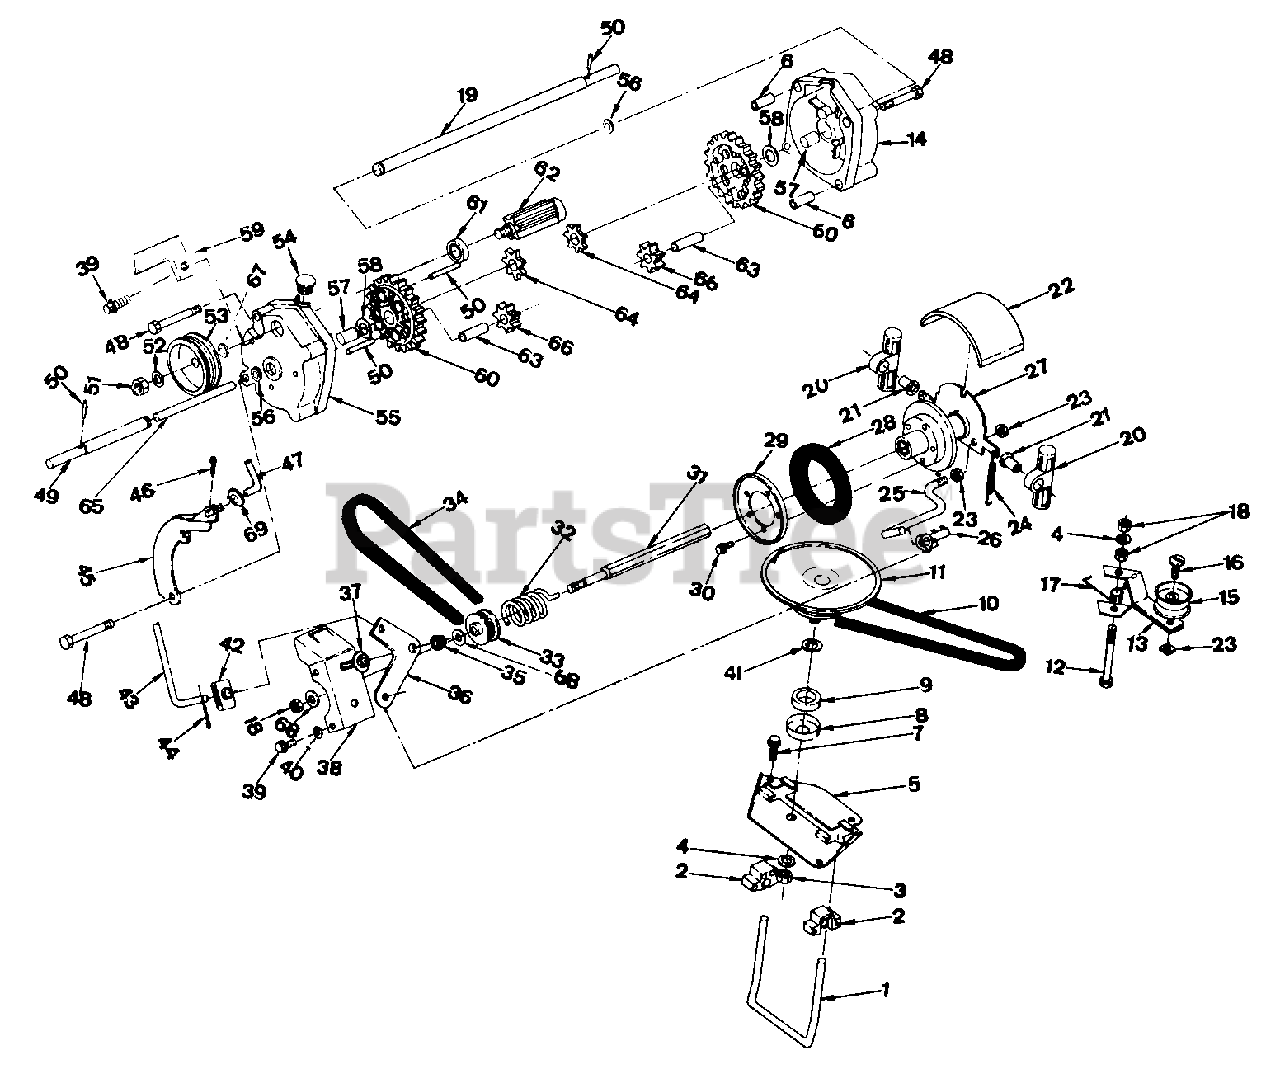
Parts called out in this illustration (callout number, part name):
1	Shift Fork
2	Pillow Block
3	3/8-24 Hex Nut
4	3/8 Int. Tooth L'Washer
5	Disc Plate
6	Roll Pin
7	5/16-18 x 5/8 HWST
8	Bearing Shield
9	Felt Seal
10	3L 255 V Belt
11	Drive Disc Ass'y.
12	3/8-24 x 3 HHCS
13	Idler Arm
14	Out Board Housing
15	Idler Pulley
16	1/4-28 x 1 1/2 FHMS
17	Idler Spring
18	3/8-24 Hex L'Nut
19	Long Axle
20	Slide Block
21	Pivot Bearing
22	Cover
23	1/4-28 Hex L'Nut
24	Clutch Spring
25	Clutch Rod
26	Clutch Rod Clip
27	Driven Disc Ass'y.
28	RING, Driven (Rubber Disc)
29	Tire Plate
30	10-24 x 5/8 SEMS St.
31	Hex Shaft
32	Rev KO Spring
33	Polly "V" Pulley, 1-9/16 Pd
34	200 J6 Polly "V" Belt
35	5/16-24 Flanged L'Nut
36	Bell Crank
37	Friction Washer
38	Bell Crank Str.
39	1/4-20 x 5/8 SEMS St.
40	1/4 SAE Washer
41	3/8 SAE Washer
42	Wear Block
43	Shift Link
44	Cotter Pin, 1/8 x 3/4
45	Transmission Release Brkt.
46	1/8 x 3/4 Cotter Pin
47	Release Rod
48	1/4-20 x 2 1/2 HHCS
49	Short Axle
50	Roll Pin, 3/16 x 1 5/8
51	7/16-20 Hex Nut
52	Spring Washer
53	Polly "V" Pulley
54	Plug
55	Inboard Housing
56	Seal
57	Bearing
58	Thrust Washer
59	Belt Guide
60	* NLA, USE 7060337 Kit, 46T, 12P. Gear
61	Ball Bearing
62	Input Gear Assembly
63	Shaft
64	12T, 12P. Gear
65	Pin
66	12T., 12P. Penion
67	Spring Washer
68	Belleville Washer
69	5/16 SAE Washer
